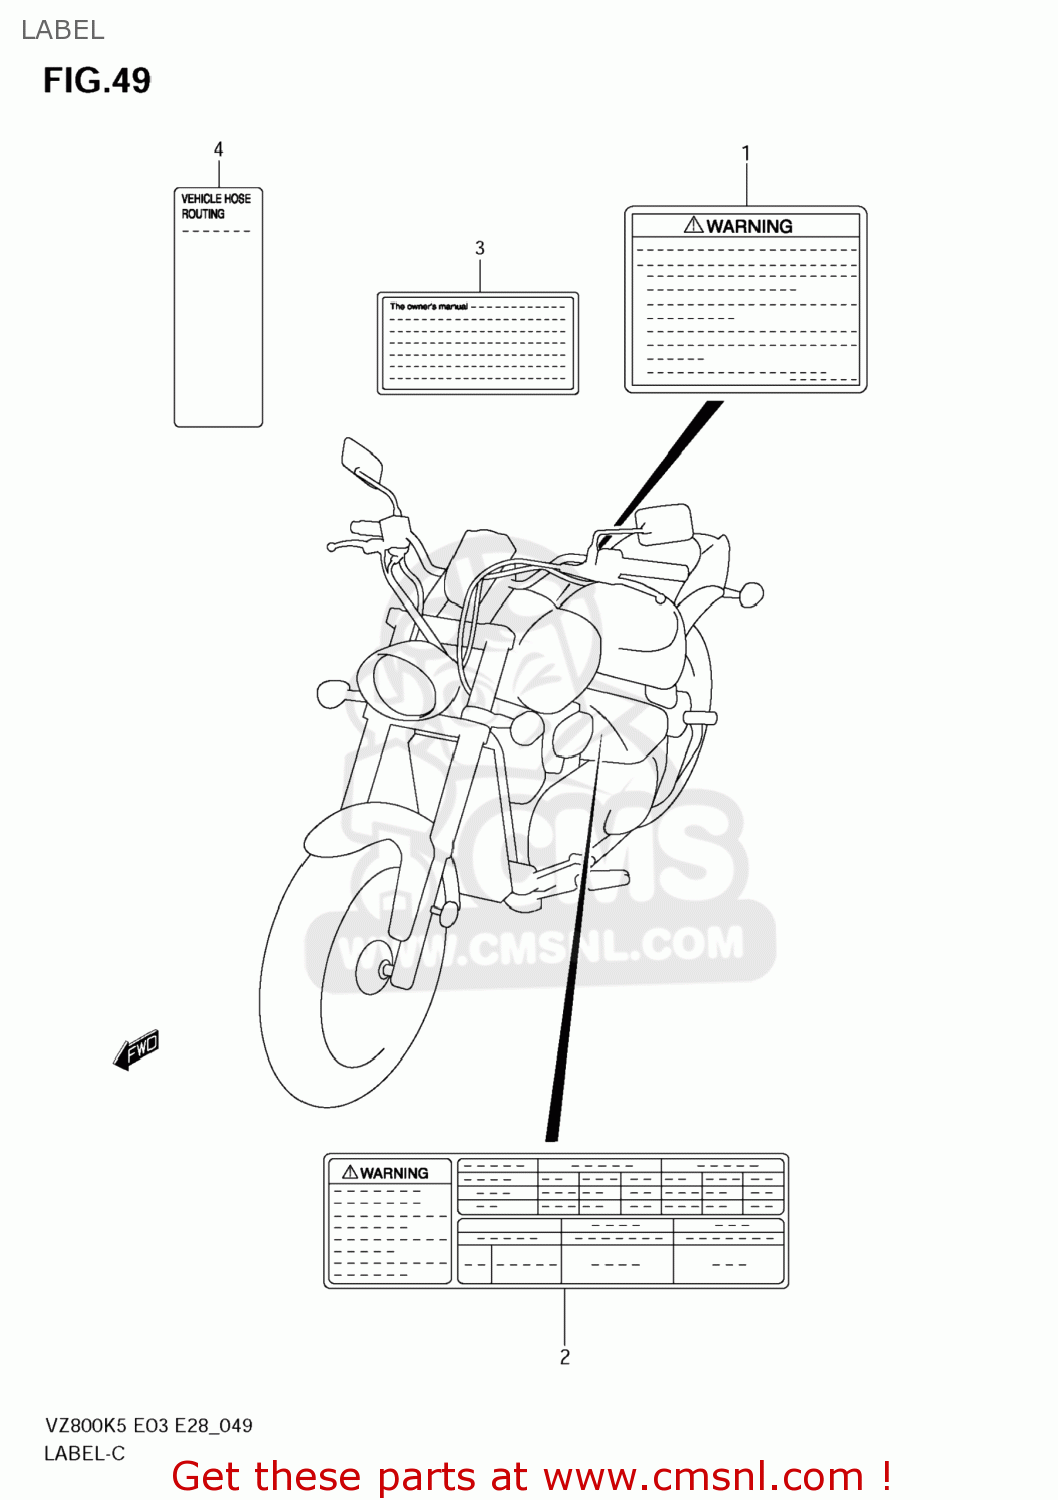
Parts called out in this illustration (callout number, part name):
1	LABEL,GENERAL WARNING
2	LABEL,TIRE INFORMATION
3	LABEL,MANUAL NOTICE
4	LABEL,VACUUM HOSE ROUTING
5	MANUAL,OWNER'S
